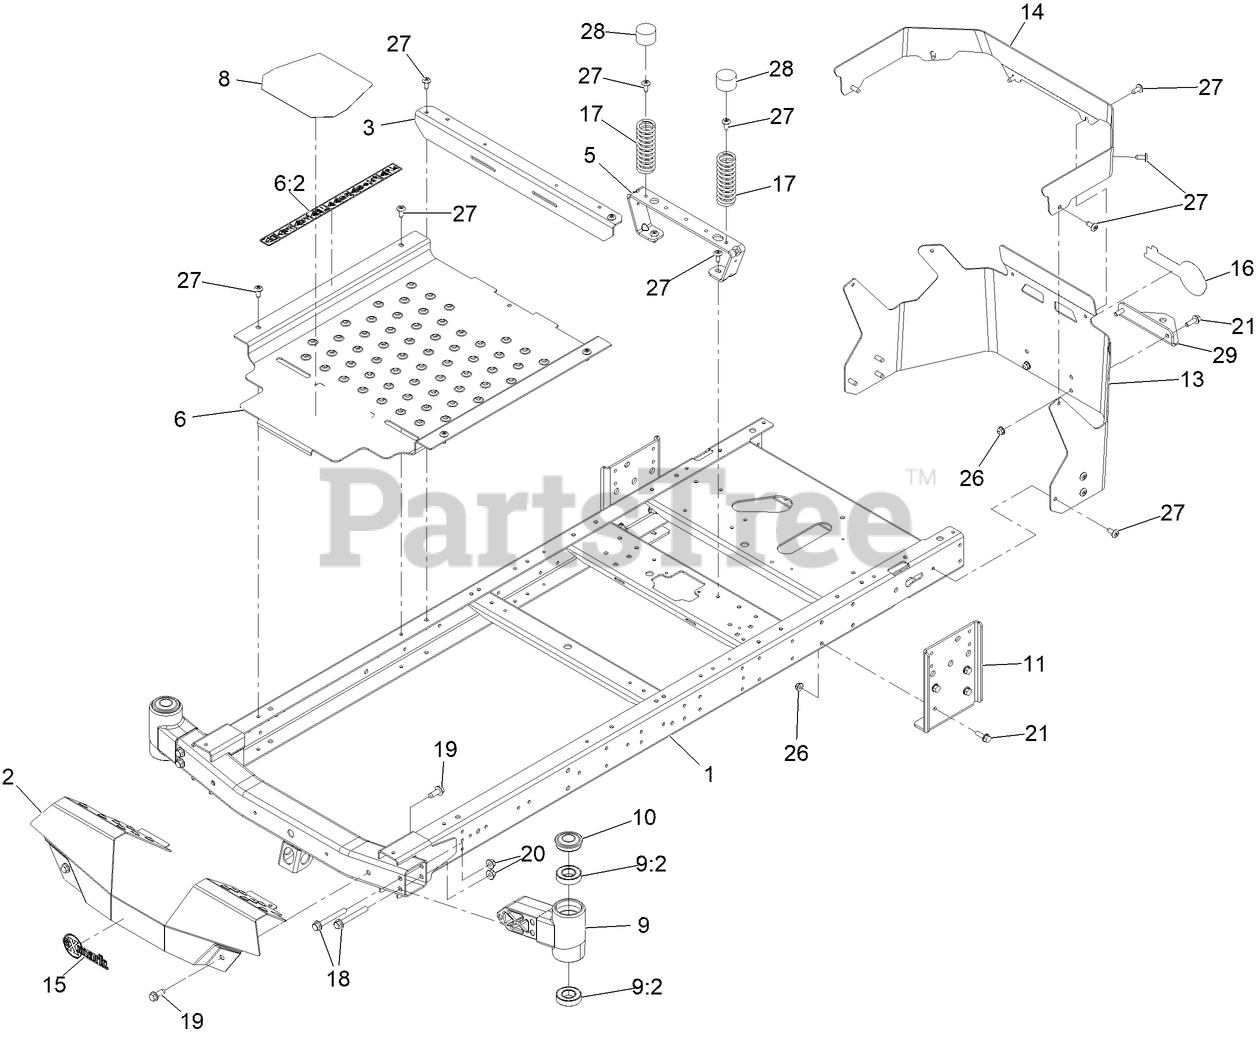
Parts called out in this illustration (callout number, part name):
1	FRAME ASM
3	BRACE-CROSS
5	SUPPORT-SEAT
6	PAN-FLOOR ASM
6:2	DECAL - WARNING
8	TREAD-STEP
9	AXLE-STUB
9:2	BEARING-BALL
10	Cap-Grease
11	PLATE-MOUNT, DRIVE
13	GUARD-REAR
14	GUARD-REAR, UPPER
15	DECAL-EXMARK LOGO
16	DECAL-EXMARK LOGO
17	SPRING-COMPRESSION
18	SCREW-HHF
19	SCREW-HWH
20	NUT-HF, NI
21	SCREW-HHF
28	CAP-PROTECTOR
29	BRACKET-HITCH
